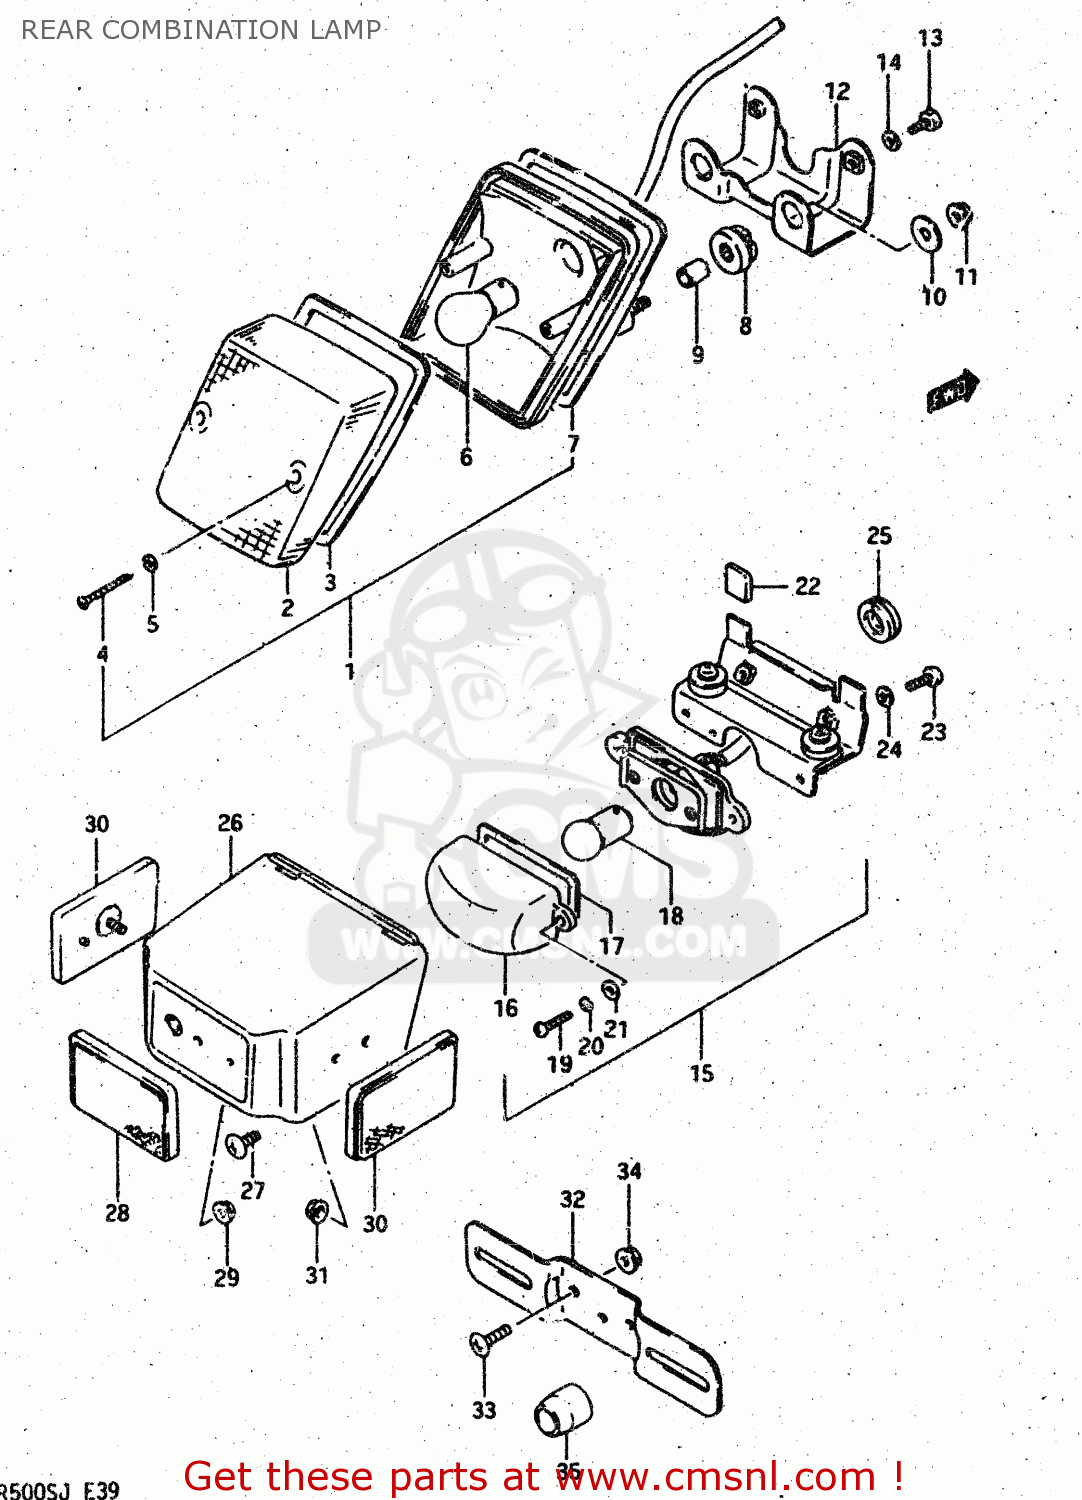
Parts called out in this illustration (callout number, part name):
1	LAMP ASSY, REAR COMBINATION
2	LENS,RR COMBI
3	GASKET,REAR COMBINATION LAMP
4	SCREW TAPP.
5	GASKET (NAS)
6	BULB(12V21/5W)
7	GASKET
8	CUSHION
9	SPACER (6.8X10X10)
10	WASHER (6.5X20X1.2)
11	NUT
12	BRACKET,REAR COMBINATION LAMP
13	BOLT
14	WASHER,LOCK
15	LAMP ASSY, LICENSE
16	LENS,LICENSE LAMP
17	GASKET,LICESE LAMP (NAS)
18	BULB(12V5W,BF150-40160A)
19	SCREW
20	WASHER,LOCK 4M
21	WASHER 4MM
22	CAP,LICENSE
23	SCREW
24	WASHER,LOCK
25	GROMMET
26	COVER,LICENSE LAMP
27	SCREW
28	RR ASSY,RR
29	NUT
30	REFLEX REFLECTOR, REAR SIDE
31	NUT
32	BRACKET, LICENSE PLATE
33	SCREW
34	NUT
35	CUSHION
